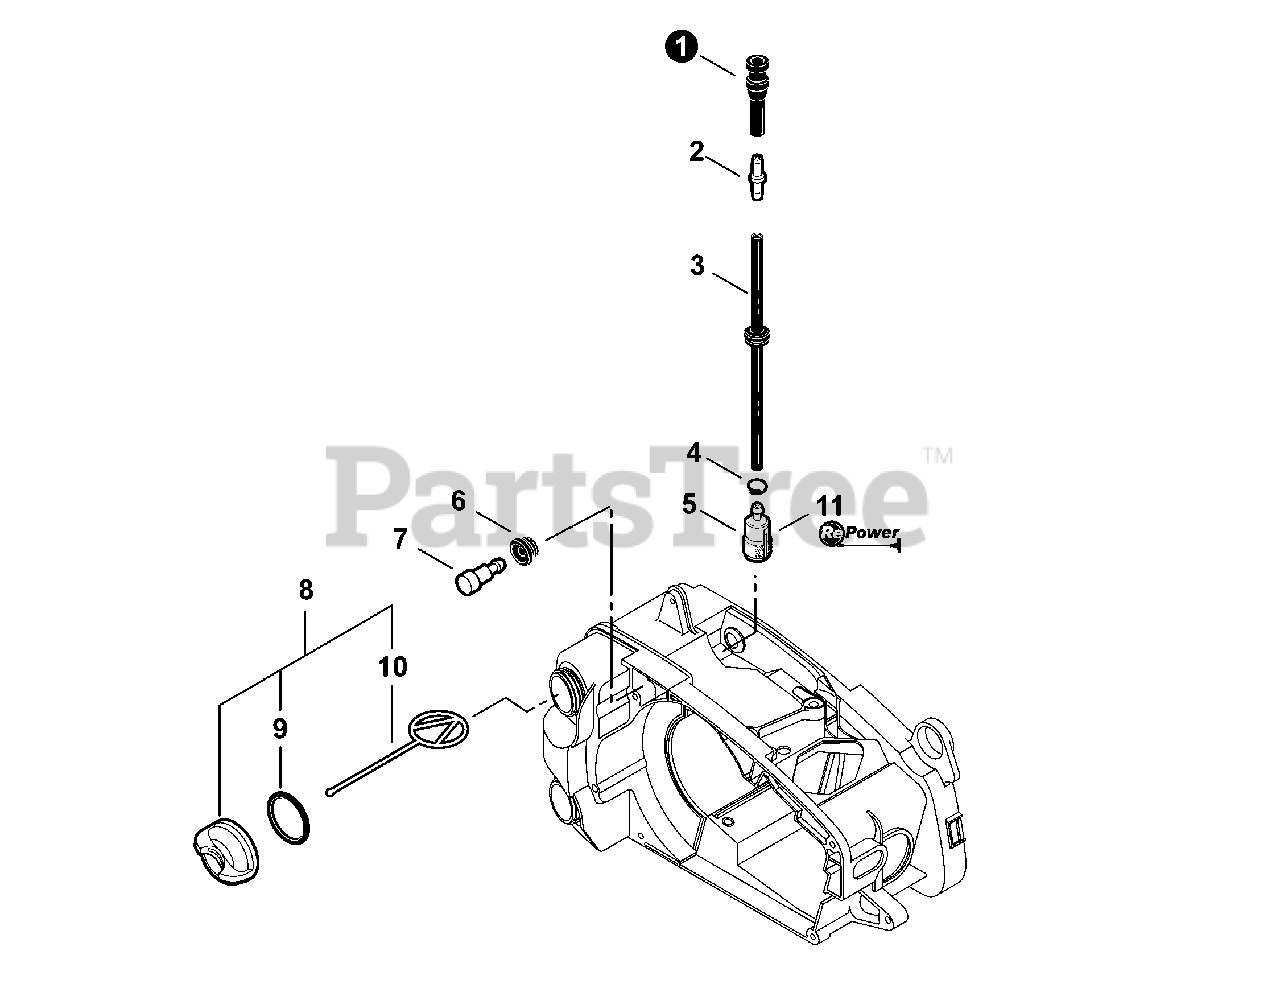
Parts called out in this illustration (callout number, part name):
1	PIPE, FUEL
2	CONNECTOR, PIPE
3	PIPE ASSY, FUEL
4	CLIP 6MM
5	FILTER, FUEL
6	GROMMET, FUEL
7	VENT ASSY
8	CAP ASSY
9	O-RING 18
10	CONNECTOR, CAP L= 60mm
11	TUNE-UP KIT - REPOWER
